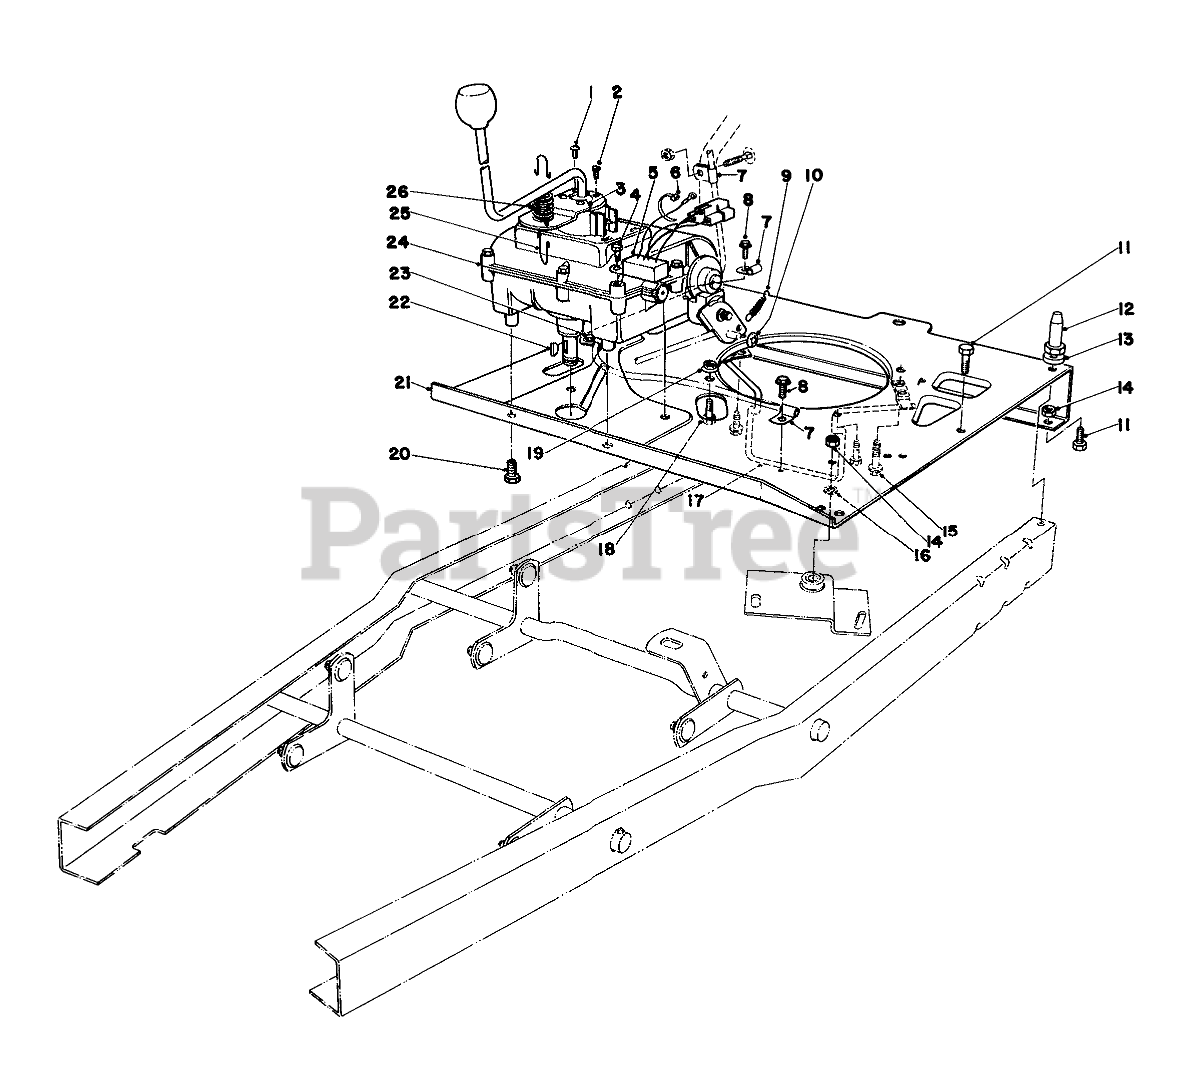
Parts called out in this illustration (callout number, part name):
3	Neutral Bracket
5	INTERLOCK MODULE
6	TIE-CABLE
7	CLIP-FUEL LINE
8	SCREW
9	SPRING-RETURN, BRAKE
10	PUSH ON SPEED NUT 1/4
11	SCREW-HH
12	PIN-MOUNTING, LOWER
13	Spacer
14	NUT-LOCK, CONE
15	SCREW-HWHTF
16	WASHER-PLAIN
17	Belt Guide
18	SCREW-HH
19	NUT-HF
20	5/16-18 X 5/8 SEMS SC
21	Plate-Engine
22	KEY-WOODRUFF
23	SCREW-HHFTF
24	Transmission
25	Neutral Spring Wire
26	SPRING
